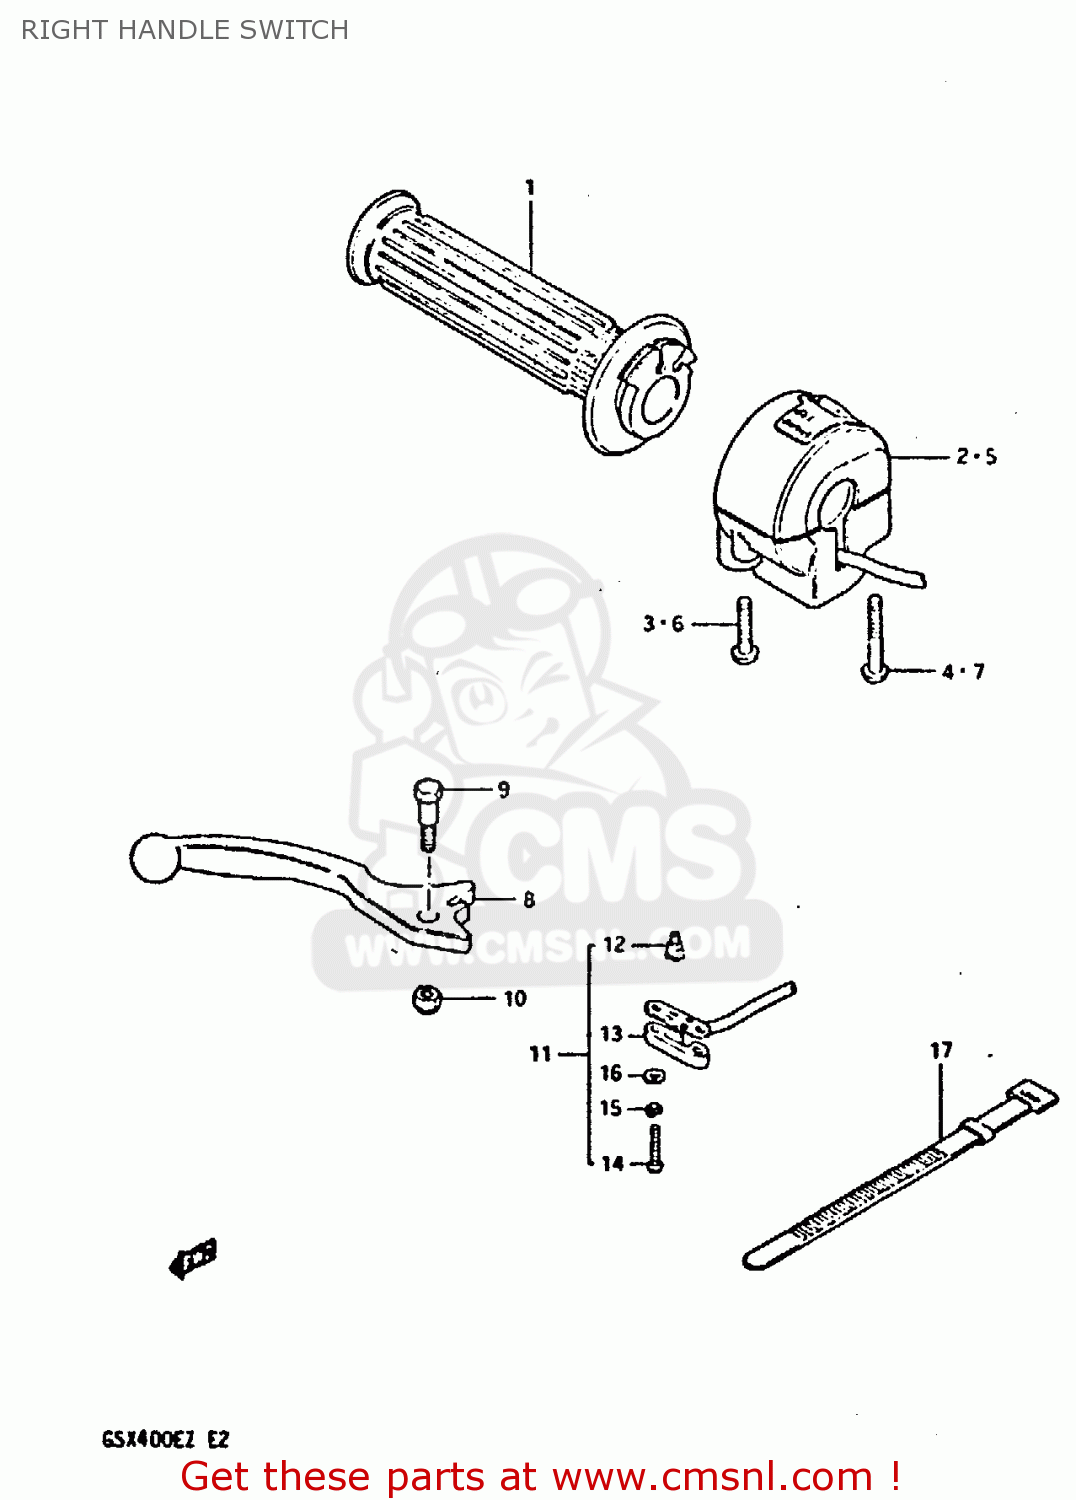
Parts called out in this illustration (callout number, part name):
1	GRIP,THROTTLE
2	SWITCH ASSEMBLY,HANDLE,RIGHT
3	SCREW
4	SCREW
8	LEVER,BRAKE
9	BOLT
10	NUT 6MM
17	CLAMP(L:120)
